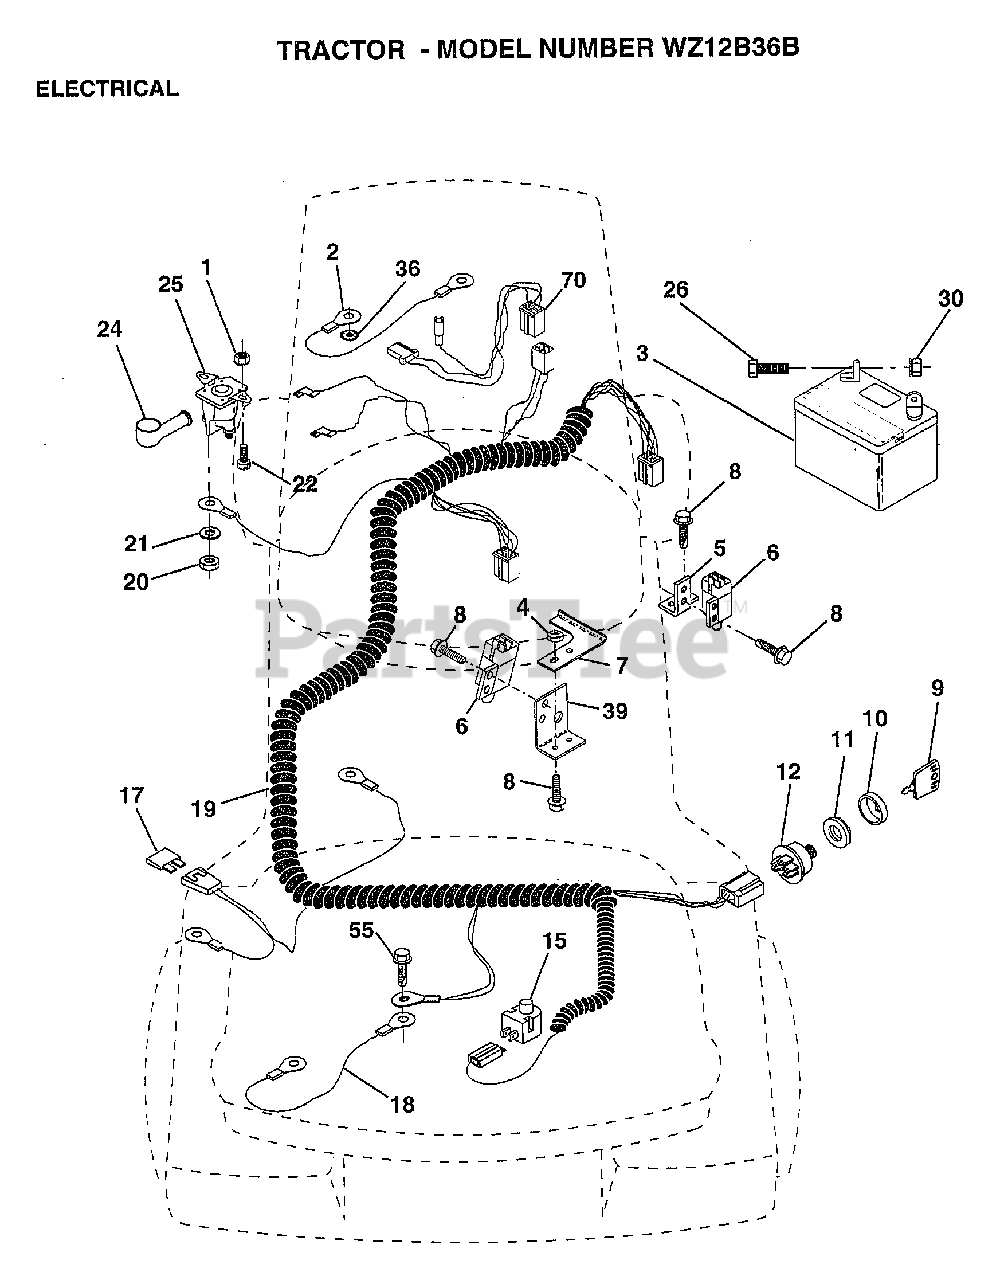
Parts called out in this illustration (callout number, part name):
1	NUT HXKEP 1/4X20
2	CABLE ASM.
4	LOCKNUT
5	BRACKET LT
6	SWITCH INTERLOCKT
7	KEEPER.ACTUAT.LR.
8	SCREW
9	KEY MLD GEN DELTA
10	COVER KEY SWITCH
12	SWITCH.IGNITION
15	SWITCH SEAT
17	FUSE HYT
18	CABLE ASSY
19	HARNESS.IGNITION
20	NUT
22	BOLT HXHD FIN
26	BOLT LT
30	NUT
36	LOCKWASHER
39	BRACKET SWT CLUTC
55	SCREW LT
70	HARNESS.ENGINE
